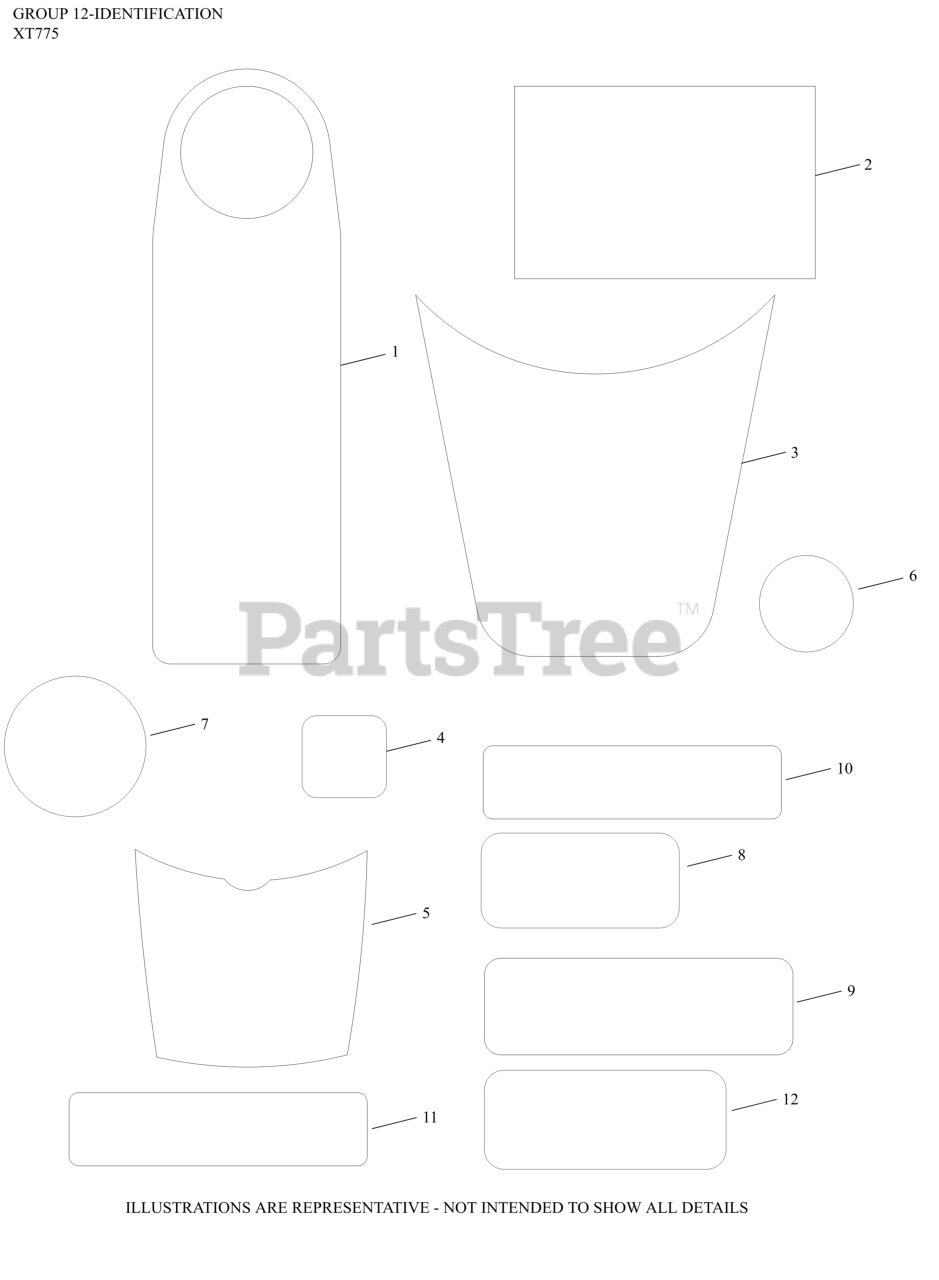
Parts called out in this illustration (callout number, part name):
2	DECAL, WARNING
2	DECAL, NAME XT775
4	DECAL, ON/OFF COURAGE XT7 (TTI)
